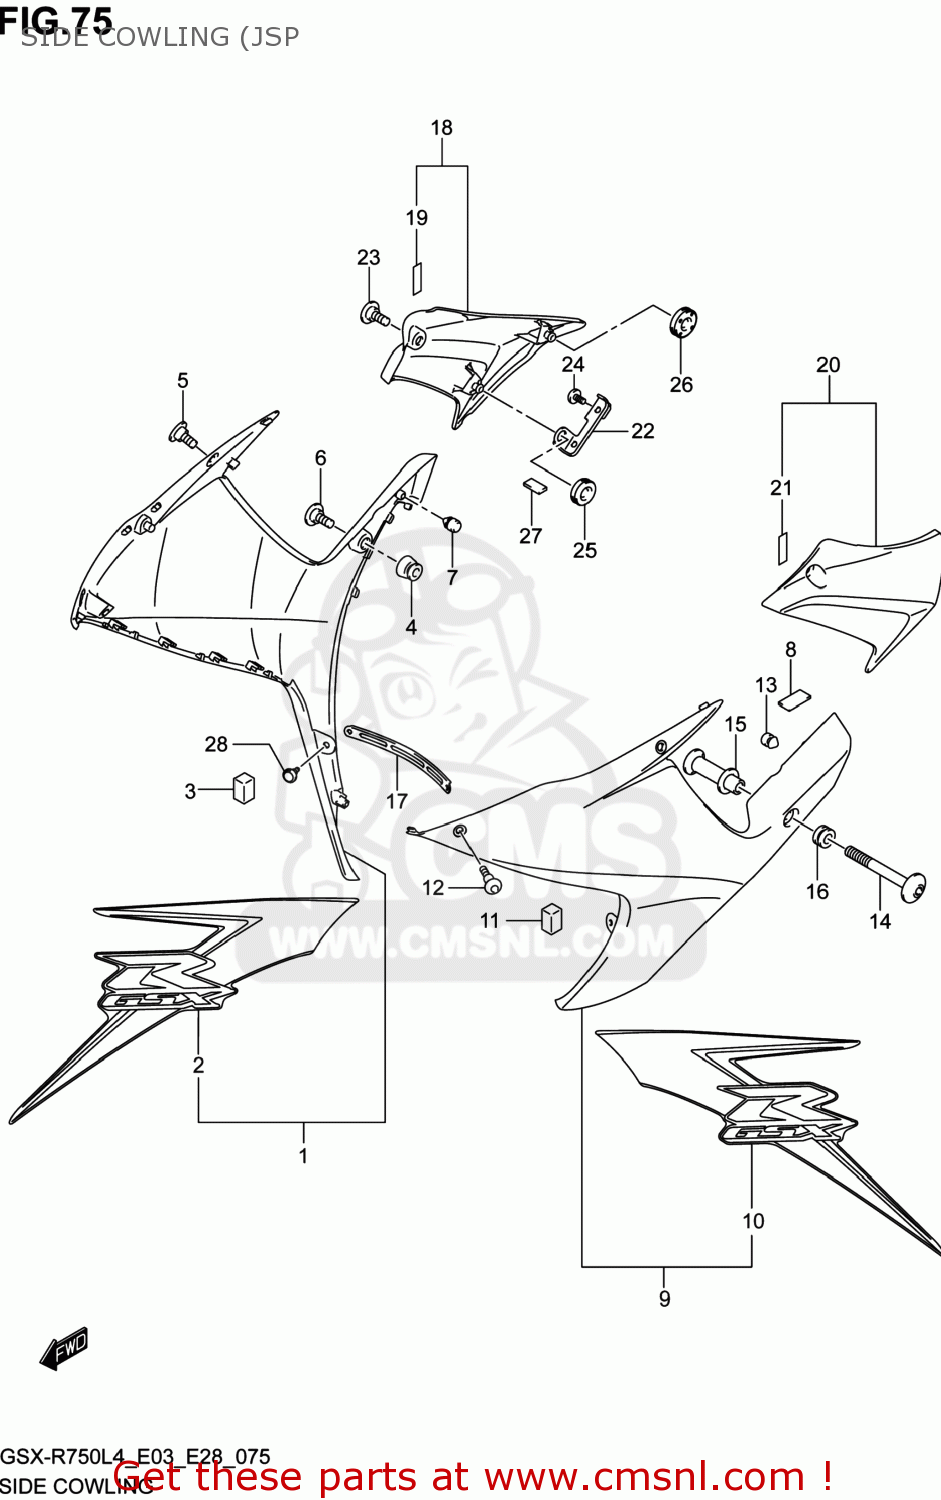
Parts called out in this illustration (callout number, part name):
1	COWLING,SIDE,R(BLACK)
2	TAPE,SIDE COWLING,R
3	CUSHION,SIDE COWL FR
4	CUSHION,UNDER COWLING,L
5	SCREW(5X13)
6	BOLT(6X20)
7	CUSHION
8	CUSHION,FUEL TANK NO.2
9	COWLING,SIDE,L(BLACK)
10	TAPE,SIDE COWLING,L
11	CUSHION,SIDE COWL FR
12	SCREW(5X13)
13	CUSHION
14	SCREW,SIDE COWL,L
15	SPACER,SIDE COWL,L
16	CUSHION
17	PLATE,UNDER COWL CTR
18	COVER,SIDE COWLING,R
19	TAPE(6X25X0.13)
20	COVER,SIDE COWLING,L
21	TAPE(6X25X0.13)
22	BRACKET,COVER SIDE,R
23	SCREW(5X13)
24	SCREW(6X12)
25	CUSHION
26	CUSHION
27	CUSHION
28	CLIP
